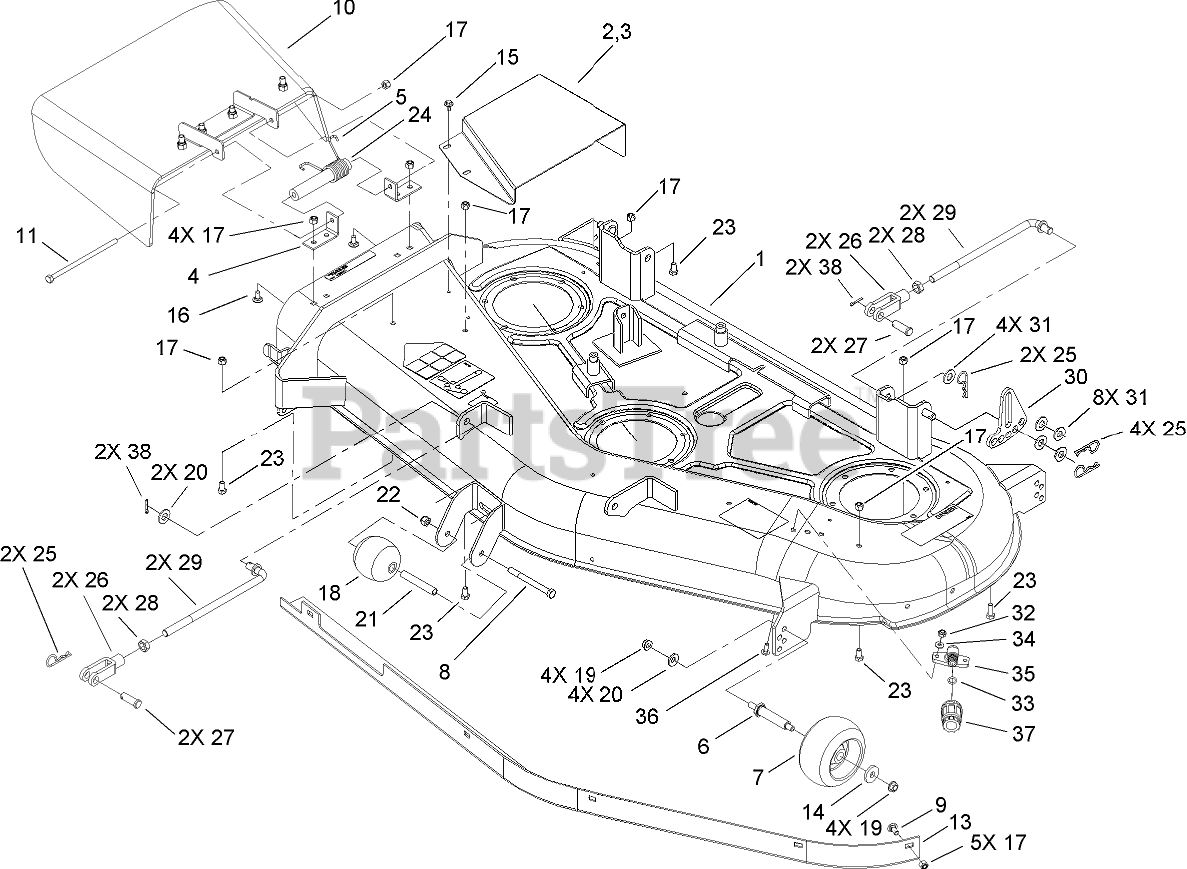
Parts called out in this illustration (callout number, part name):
1	52 INCH DECK ASM
3	COVER-BELT, RH
4	BRACKET-PIVOT, DEFLECTOR
5	SPRING-TORSION
6	SPACER
7	ROLLER-SCALP, ANTI
8	SCREW-HH
9	SCREW-CARR
10	DEFLECTOR ASM
11	BOLT-HH
14	WASHER
15	SCREW-HHFTF
16	SCREW-CARR
17	NUT-LOCK, NI
18	ROLLER
19	NUT-HHF, WHIZ
20	WASHER-BELLEVILLE
21	TUBE-SPACER, WHEEL
22	NUT-LOCK, NI
23	SCREW-HH
24	SPACER-DEFLECTOR
25	PIN-COTTER
26	CLEVIS
27	PIN-CLEVIS
28	NUT-JAM
29	ROD-TRUNION
30	LINK-HOC, ADJUSTING
31	WASHER-FLAT
32	NUT-LOCK, NI
33	O-RING
34	WASHER-FLAT
35	FITTING-WASHOUT
36	BOLT-CARR
37	CONNECTOR-HOSE
38	PIN-COTTER
